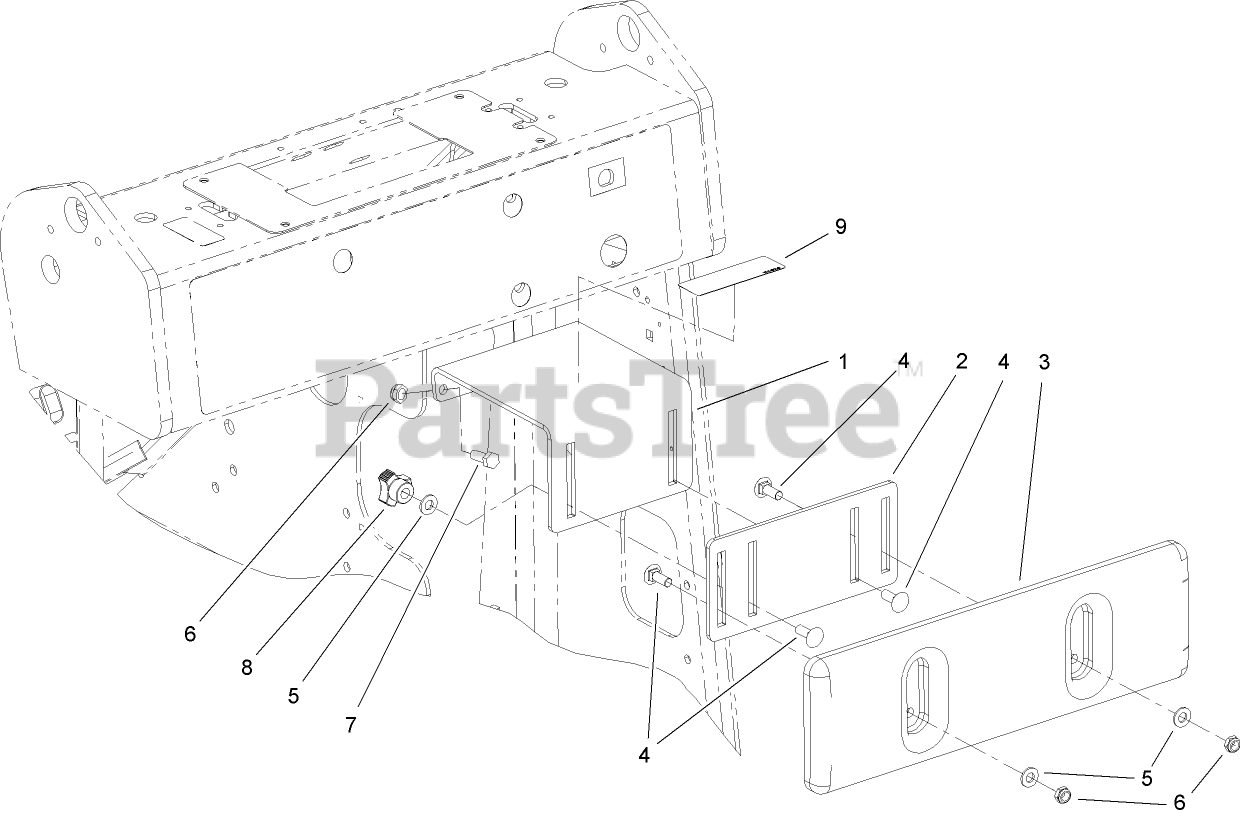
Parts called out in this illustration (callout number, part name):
1	Thigh Support ASM
2	PLATE-ADJUSTING
3	SUPPORT-THIGH
4	SCREW-CARR
5	WASHER-FLAT
6	NUT-LOCK, NI
7	SCREW-HH
8	Knob-Adjustment
9	DECAL-MANUAL
